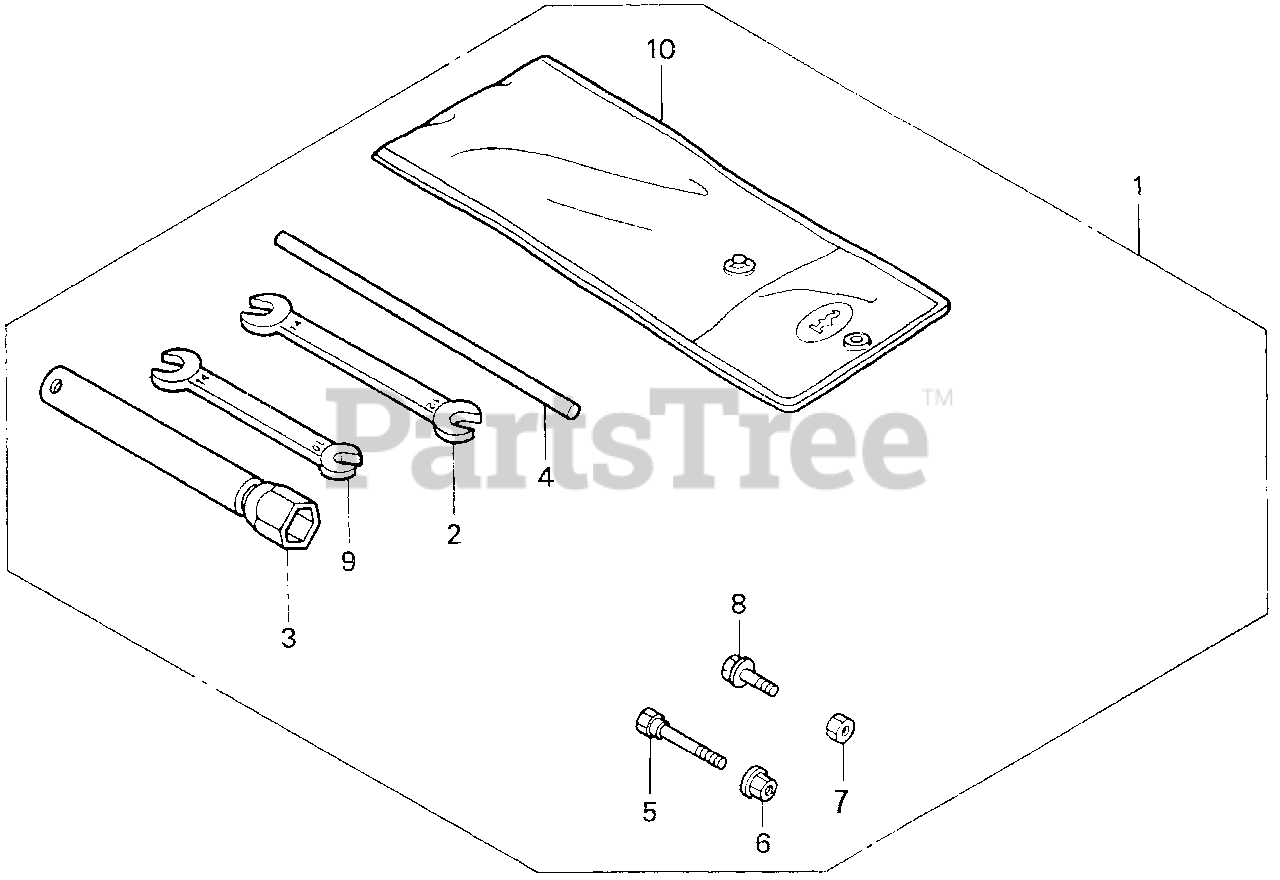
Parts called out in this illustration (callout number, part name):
2	SPANNER (12X14)
3	WRENCH, SPARK PLUG
4	HANDLE, BOX WRENCH
5	BOLT, LOCK
6	NUT, SELF-LOCK (6MM)
7	NUT, HEX. (6MM)
8	BOLT, FLANGE (6X16)
9	SPANNER (10X14)
